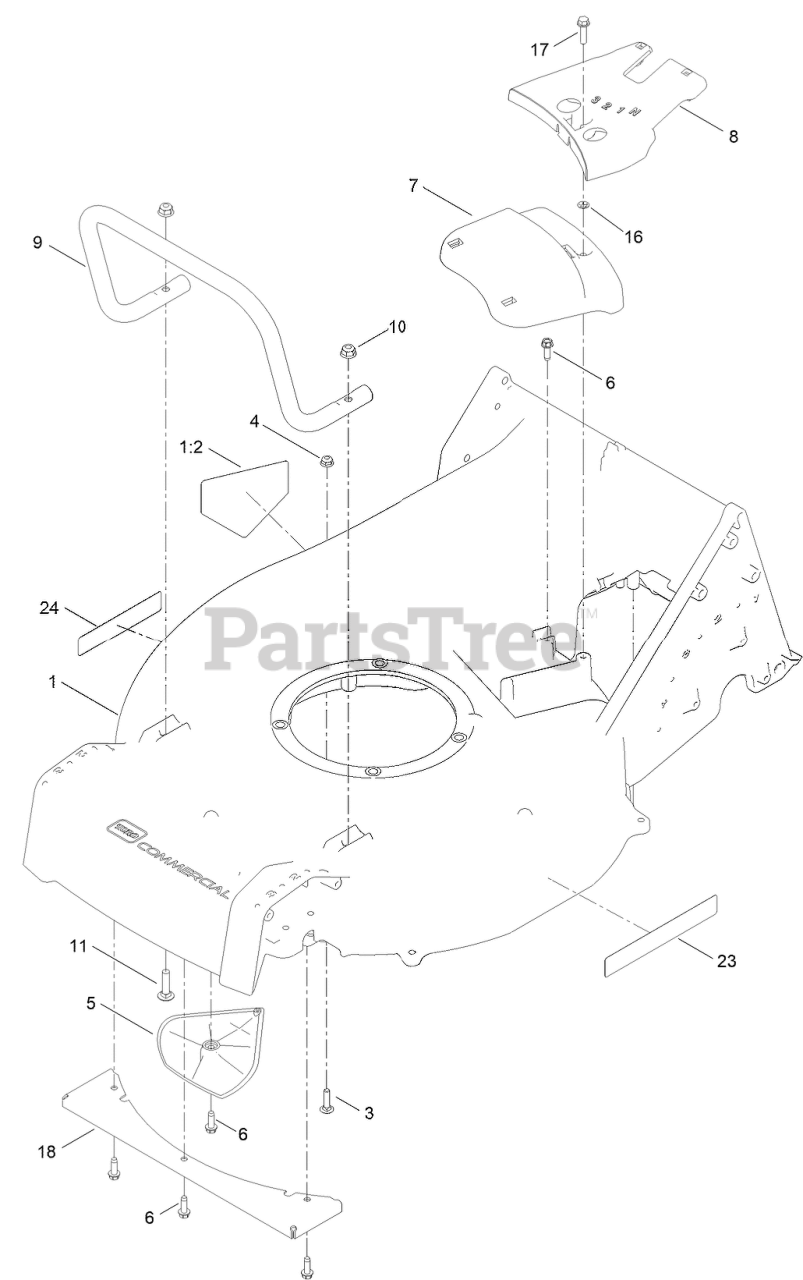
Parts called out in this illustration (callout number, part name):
1	HOUSING ASM
1:2	DECAL-DANGER
3	SCREW-CARR
4	NUT-HF
5	KICKER
6	SCREW-HWHTF
7	COVER-BELT, FRONT
8	COVER-BELT, REAR
9	GUARD-ENGINE
10	NUT-HF, NI
11	SCREW-CARR
16	PUSHNUT-RETAINER, BOLT
17	SCREW-HWHTF
18	GUARD-TOE, FRONT
23	DECAL-RECYCLER
